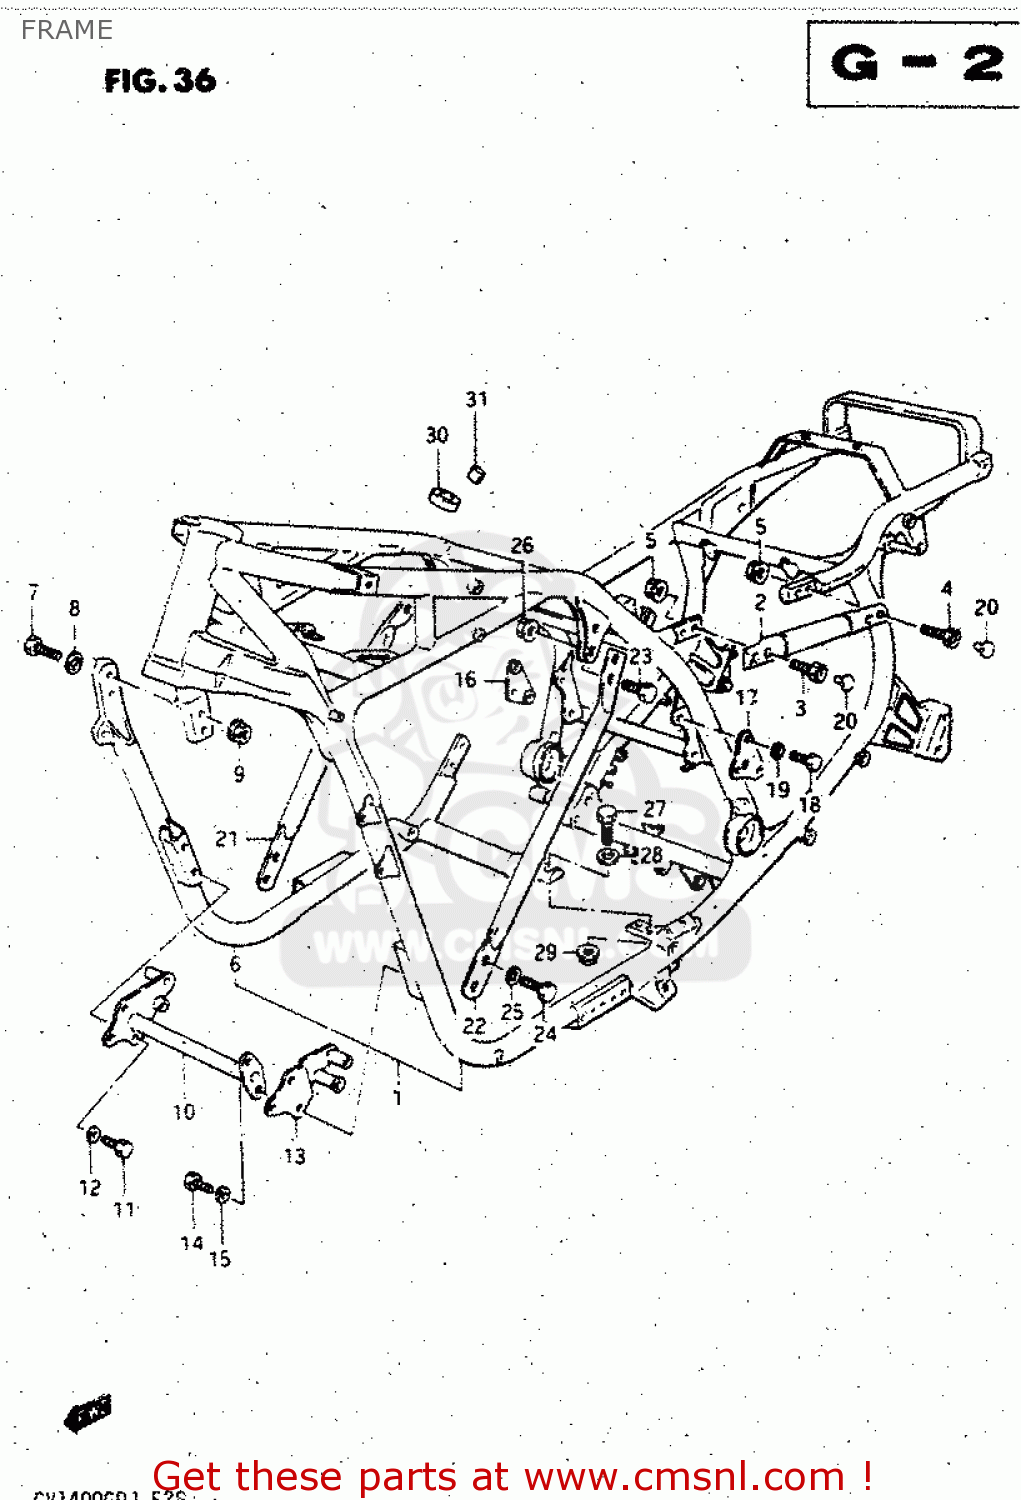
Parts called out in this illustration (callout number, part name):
1	FRAME
2	TUBE, FRAME UPPER (BLACK)
3	BOLT 10X25
4	BOLT
5	NUT 10MM
6	TUBE,FRAME
7	BOLT 10X38
8	WASHER
9	NUT 10MM
10	PLATE COMP,ENGINE MOUNTING
11	BOLT
12	WASHER,LOCK,8.
13	PLATE,ENGINE MOUNTING
14	BOLT
15	WASHER,LOCK,8.
16	PLATE,ENGINE MOUNTING
17	PLATE,ENGINE MOUNTING
18	BOLT
19	WASHER,LOCK,8.
20	CAP
21	ROD,GRIP,LEFT
22	GRIP,FRAME HANDLE,LEFT
23	BOLT, UPPER
24	BOLT
25	WASHER,LOCK
26	NUT 10MM
27	BOLT(10X33)
28	WASHER
29	NUT 10MM
30	CUSHION,FRAME COVER
31	CUSHION,FRAME COVER
